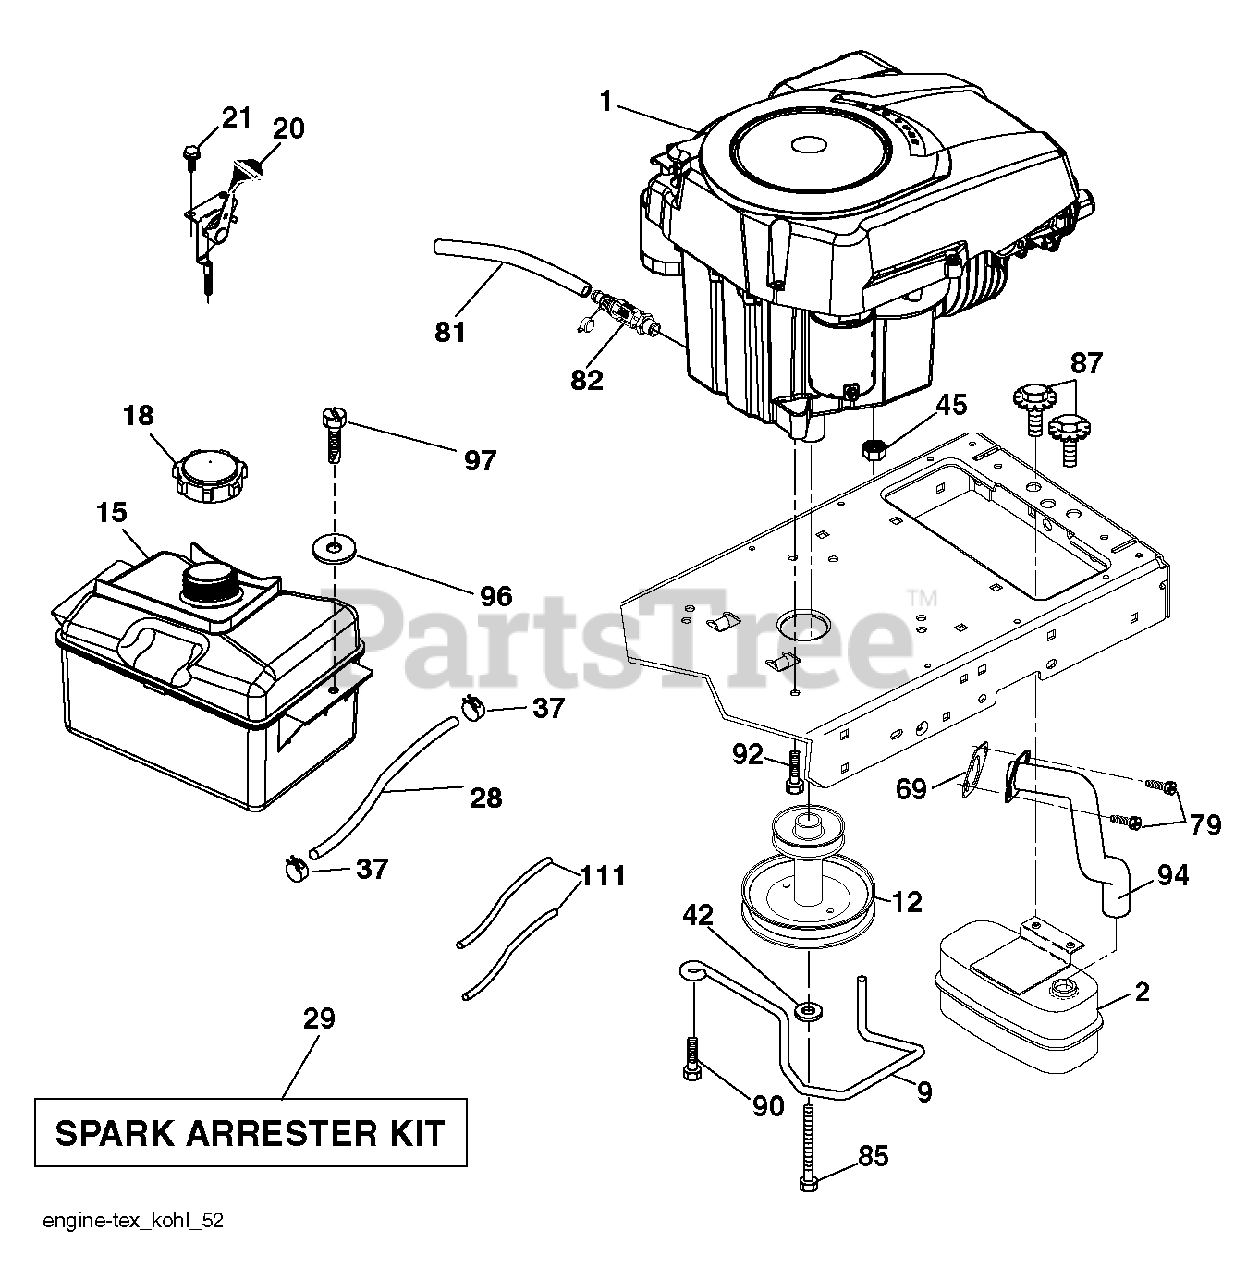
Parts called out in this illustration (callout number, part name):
9	KEEPER.BELT.ENGINE.4.2
21	SCREW.#10 X 0.750.BOS THREAD
29	ARRESTER SPARK (OPTIONAL)
37	HOSE CLAMP
42	LOCKWASHER
79	SCREW.SOCKET HD.5/16-1
81	TUBE, DRAIN OIL ASM.
82	VALUE.OIL.DRAIN
87	BOLT, 5/16-18 X 1 3/4
90	SCREW 3/8-16X1
92	SCREW 3/8-16X1
97	SCREW HEXWSHR 1/4-20X3/4
